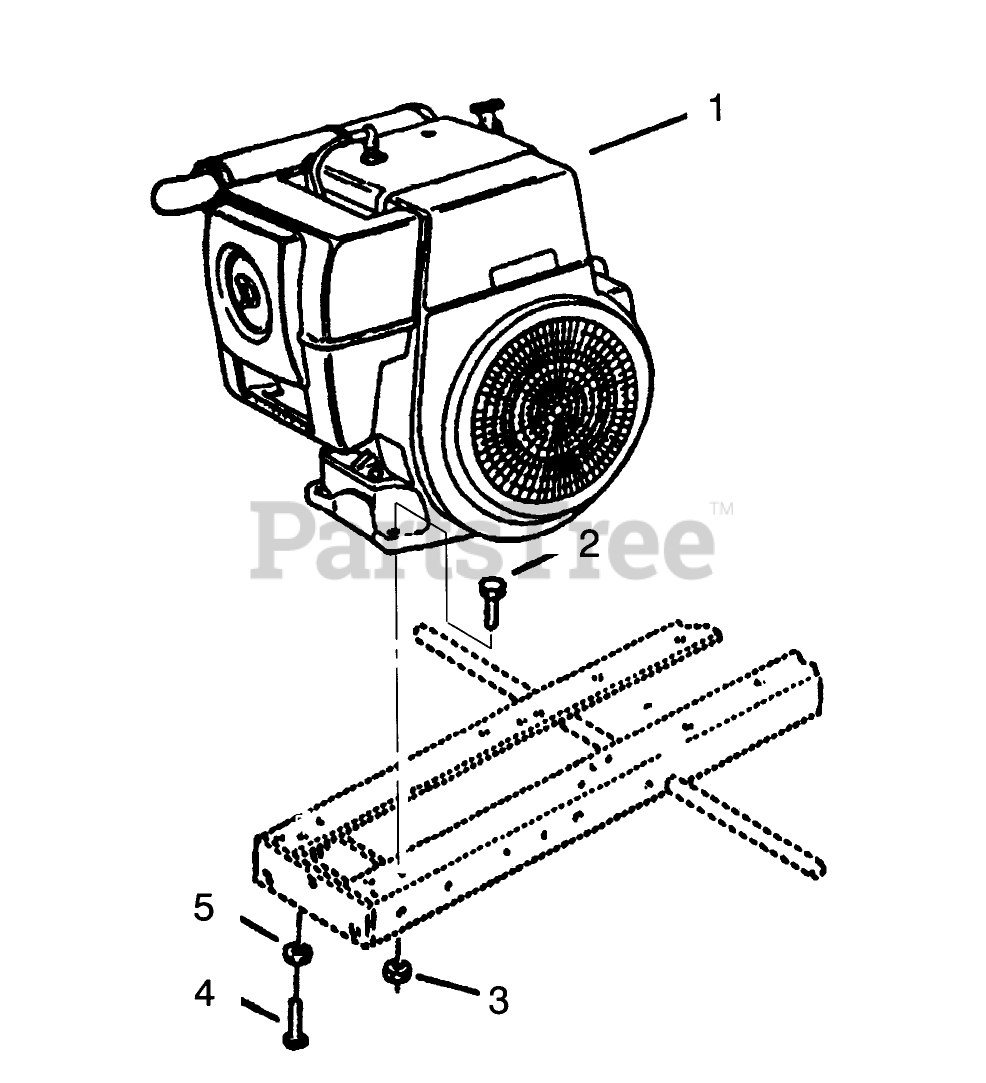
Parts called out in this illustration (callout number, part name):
1	Engine-10 HP
2	SCREW-HH
3	NUT-LOCK, NI
4	SCREW-HH
5	WASHER-LOCK
